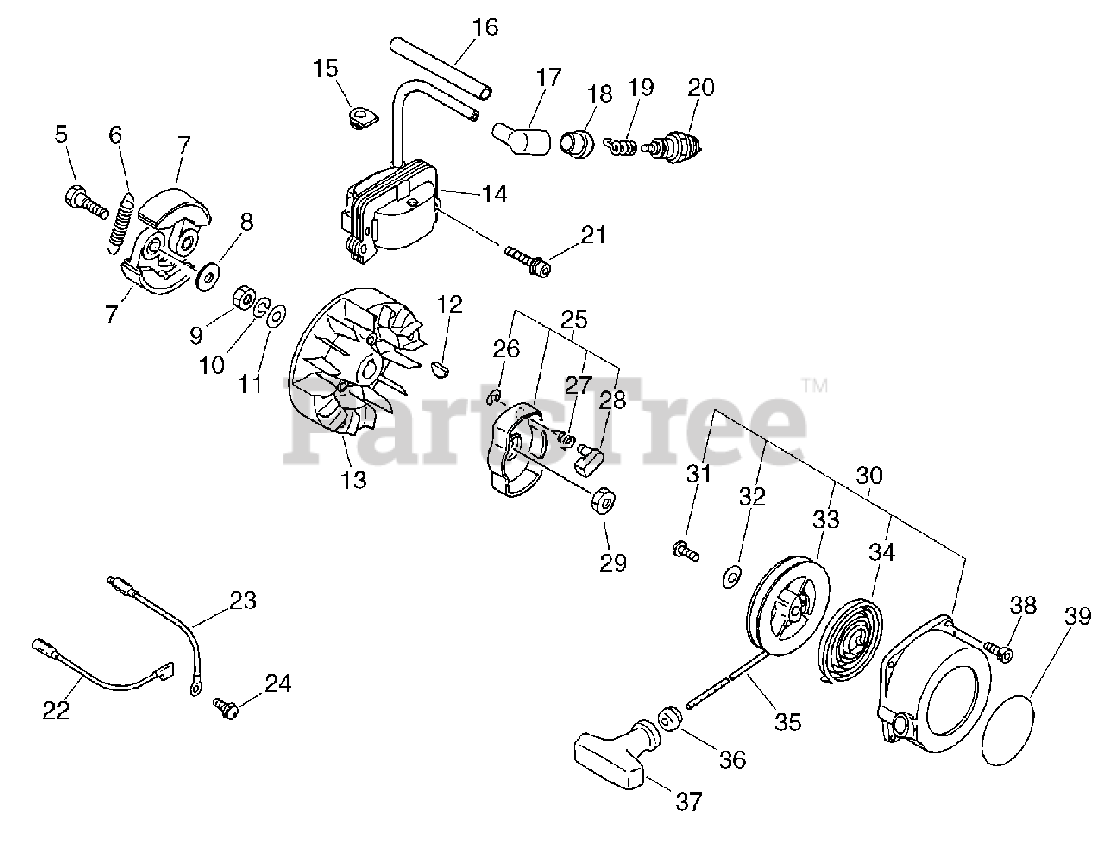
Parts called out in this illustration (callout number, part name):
5	BOLT, CLUTCH
6	SPRING, CLUTCH
7	SHOE, CLUTCH
8	WASHER - 6
10	LOCKWASHER - 8
11	WASHER - 8
13	FLYWHEEL
14	COIL, IGNITION
17	CAP, SPARK PLUG
18	COVER, PLUG CAP
19	TERMINAL, SPARK PLUG CAP
20	SPARK PLUG -- BPMR-7A
21	SCREW - 5X20
22	LEAD - GROUND
22	LEAD - IGNITION
23	LEAD - GROUND
24	SCREW - 5X10
25	STARTER PAWL ASSY
26	RING, RETAINING - 4
27	SPRING, RETURN
28	PAWL, STARTER
30	STARTER ASSY
33	REEL, ROPE
34	SPRING, REWIND
35	ROPE, STARTER - 4X950
36	GUIDE, ROPE
37	GRIP, STARTER
38	SCREW - 4X30
39	LABEL - ECHO
